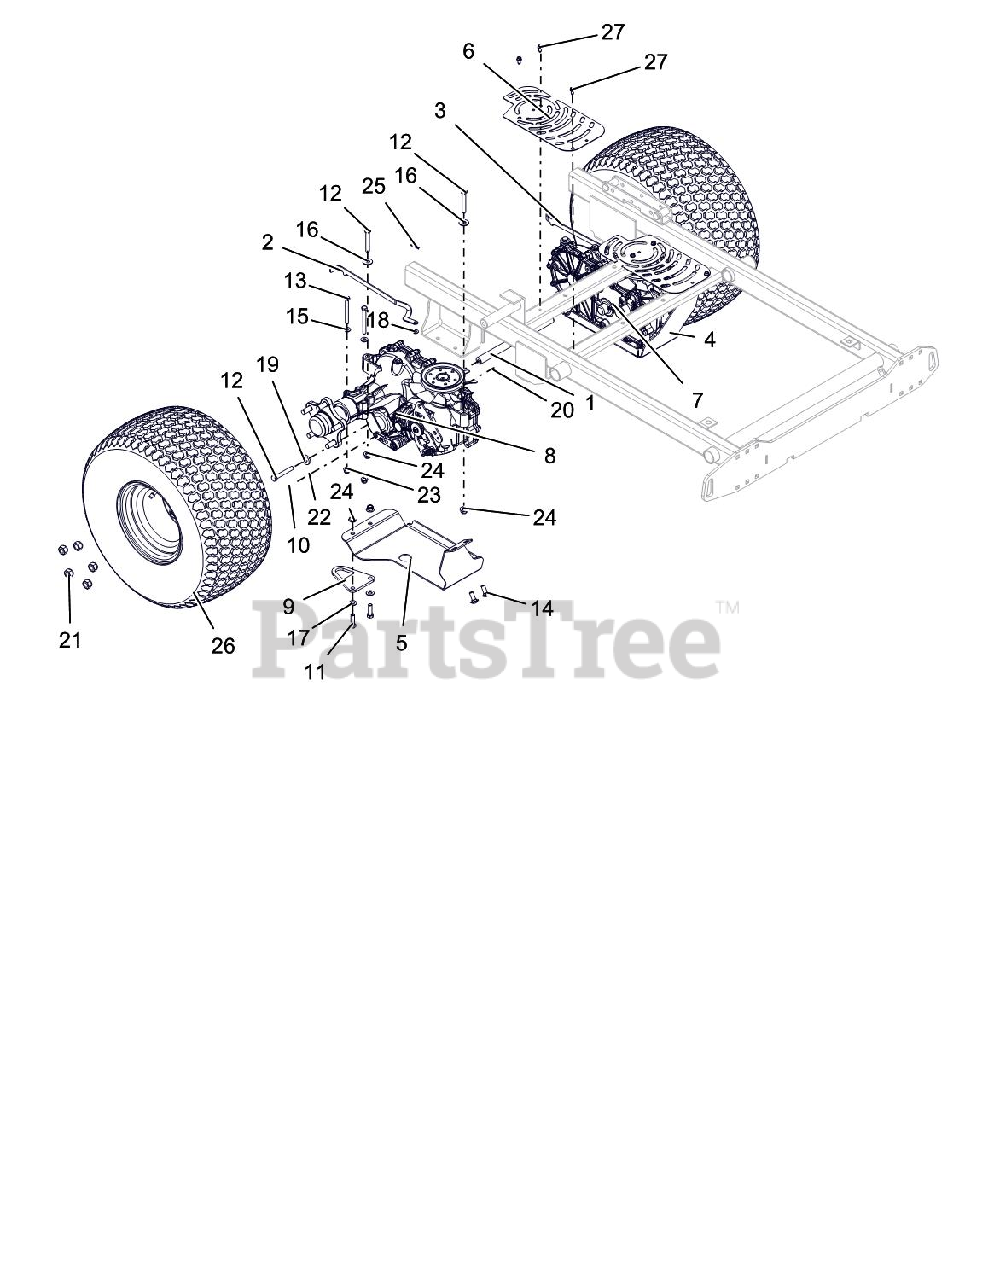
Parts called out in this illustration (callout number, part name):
1	SHAFT, CROSS BRACE
2	BRKT, LH DUMP VALVE
3	BRKT, RH DUMP VALVE
4	PLATE, LH SKID
5	PLATE, RH SKID
6	GUARD, PROSTANCE FAN
7	TRANSAXLE, ZT3400, LH
8	TRANSAXLE, ZT3400, RH
9	BRKT, TIE DOWN
10	@BLT-HEX .31-18X1.00 GR5 YWZC
11	@BLT-HEX .38-16X1.25 GR5 YWZC
12	@BLT-HEX .38-16X2.50 GR5 YWZC
13	@BLT-HEX .31-18X3.00 GR5 YWZC
14	@BLT-RDHDSQNK .38-16X1.00 G5YZ
15	@WSHR-FL-STL.312X.734X.065 YWZ
16	@WSHR-FL-STL.438X1.00X.083 YWZ
17	@WSHR-FL-STL.406X.812X.065 YWZ
18	@WSHR-FL-STL.281X.62X.065 YWZC
19	WSHR-FL-STL .406X1.00X.188 YWZ
20	@NUT-LK-CTR-JAM .31-18 YWZC
21	WHEEL NUT .500-20 YZ
22	@NUT-SPNLK-FLG .312-18 YWZC
23	@NUT-LK-NYL-FLG .31-18 YWZC
24	@NUT-LK-NYL-FLG .38-16 YWZC
25	PIN-HAIR, ENDRIES #25 YWZC
26	ASM, WHL/TIRE 20X10.5-8 RADIAL
27	SCR-TAP .25-20X.50 HWH TR YWZ
